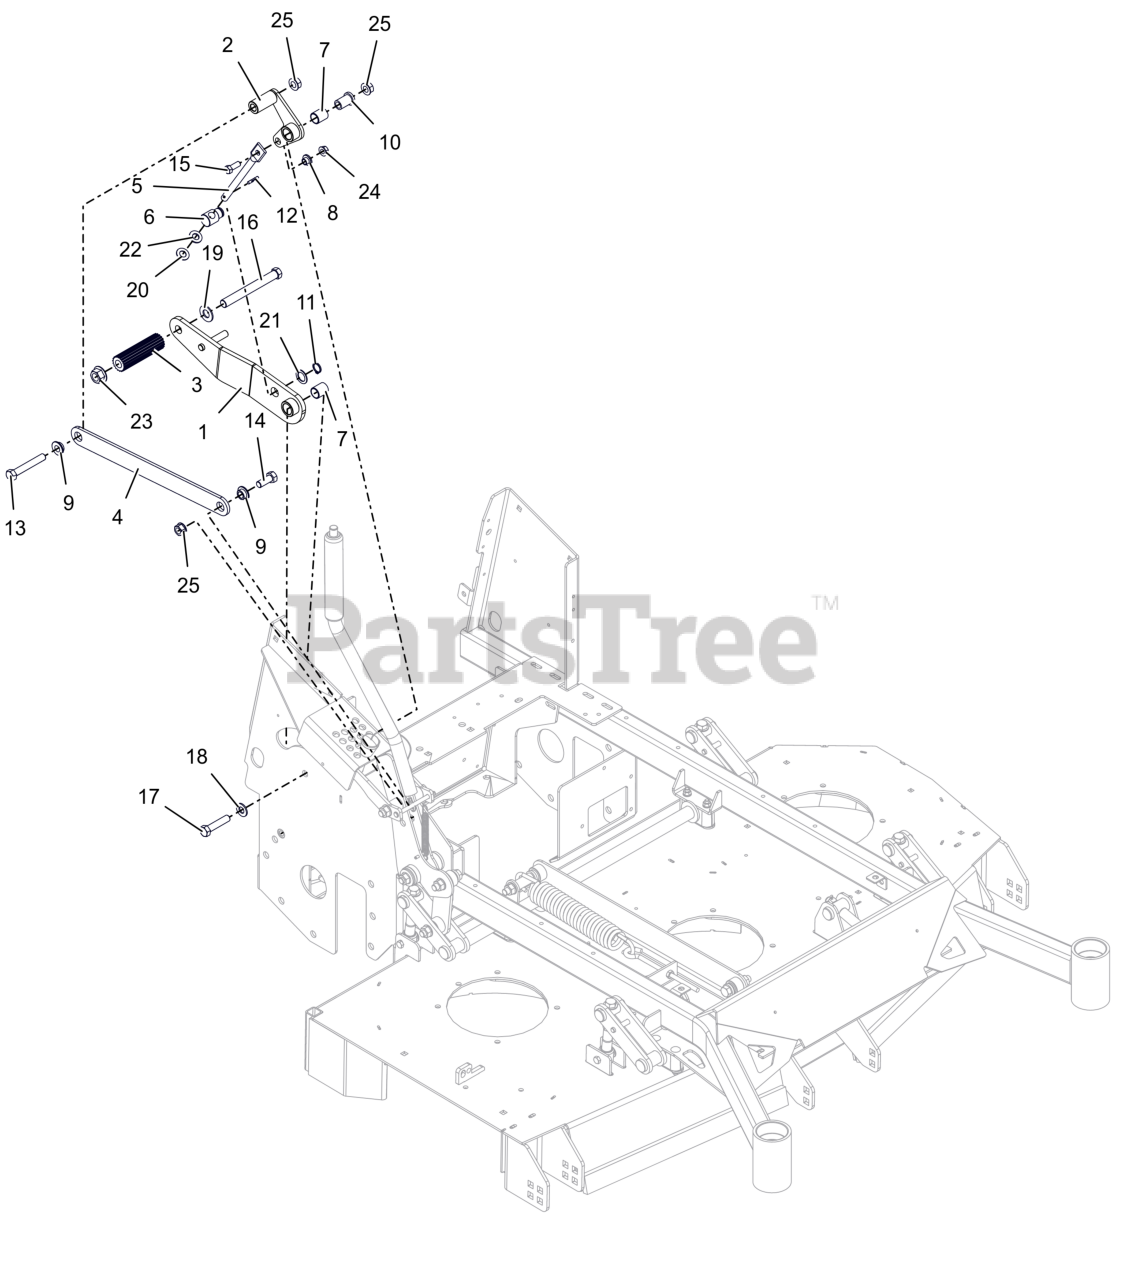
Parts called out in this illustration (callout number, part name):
1	WLDMT, DECK LIFT FOOT ASSIST (BLACK)
2	WLDMT- PIVOT BRKT
3	ROD, FOOT PEDAL (BLACK)
4	LINK-DECK LIFT FOOT ASSIST
5	LINK, HOC FOOT
6	TRUNNION-DECK LIFT FOOT ASSIST
7	BRG, .750 X .875 X 1.000
8	BSHG-FLG .385X.500X.875X.406
9	BSHG, FLANGE .515X.750X.420X1.12
10	BSHG-FLG .515X.746X1.290X1.000
11	RG-RTNG-EXT .689X.078
12	PIN-GRV .188X1.00 TP E
13	BLT,HEX .50-13X3.25 G5 ZCC
14	BLT,HEX .50-13X1.25 G5 ZCC
15	BLT,HEX .38-16X1.00 G5 ZCC
16	BLT, HEX .62-11X5.50 G5 FBP
17	BLT, HEX .50-13X2.25 G5 ZCC
18	WSHR,FLT .531X1.062X.095 ZCC
19	WSHRFLT 5/8SAE CARBHARD FBP
20	WSHR, FLT .531X1.00X.063 ZCC
21	WSHR, FLT .754X1.125X.062 ZCC
22	WSHR, RUBBER .531 X 1.000 X .094
23	NUT,FLG-TOP LK .625-11 FBP
24	NUT-LK-CTR-FLG .375-16 GF ZCC
25	NUT-LK-CTR-FLG .500-13 GG ZCC
